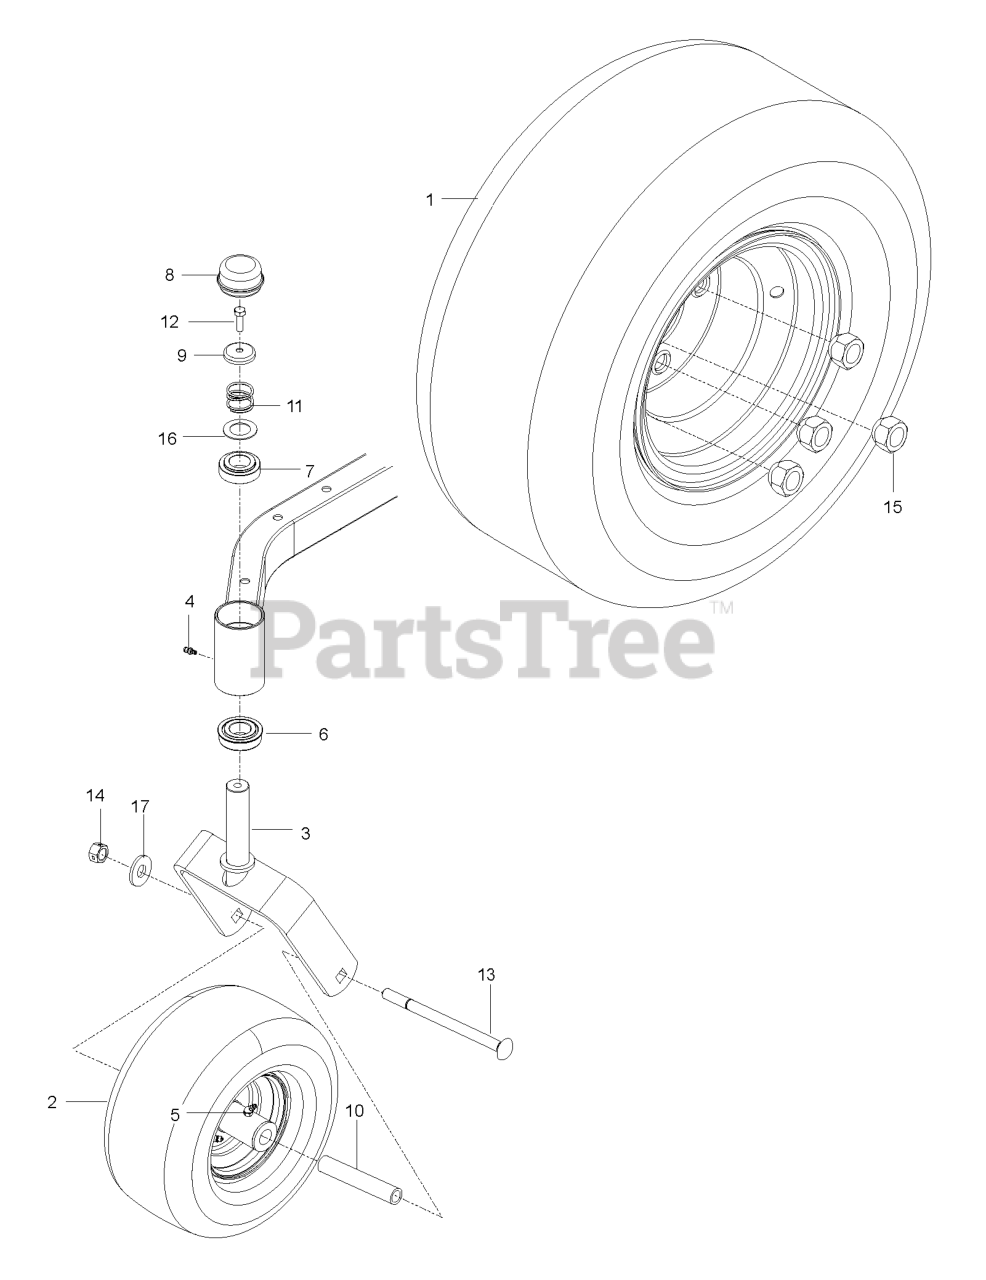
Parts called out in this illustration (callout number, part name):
1	WHEEL.CARLSTAR.18X8.5-8".MS417
2	WHEEL ASSY, WIDE, RZ
3	YOKE.PNT.CASTER.ORG
4	ZERK, 3/16, DRIVE IN
5	ZERK
6	BEARING FLANGED
7	BUSHING, CASTER
8	GREASE CAP
9	CASTER.PLUG
10	SPACER.PIVOT
11	SPRING, CASTER
12	5/16-18X1 HHB G5W/NY
13	RHSNB 1/2-13 X 7.5
14	NUT. 1/2-13 HEX CNTRLK GR 5 ZD
15	NUT.1/2-20.UNF-2B.GR.8.YL
16	WASHER, 1.025 ID X 1.64
17	WASHER.9/16 X 1 3/8 X 12 GA.
